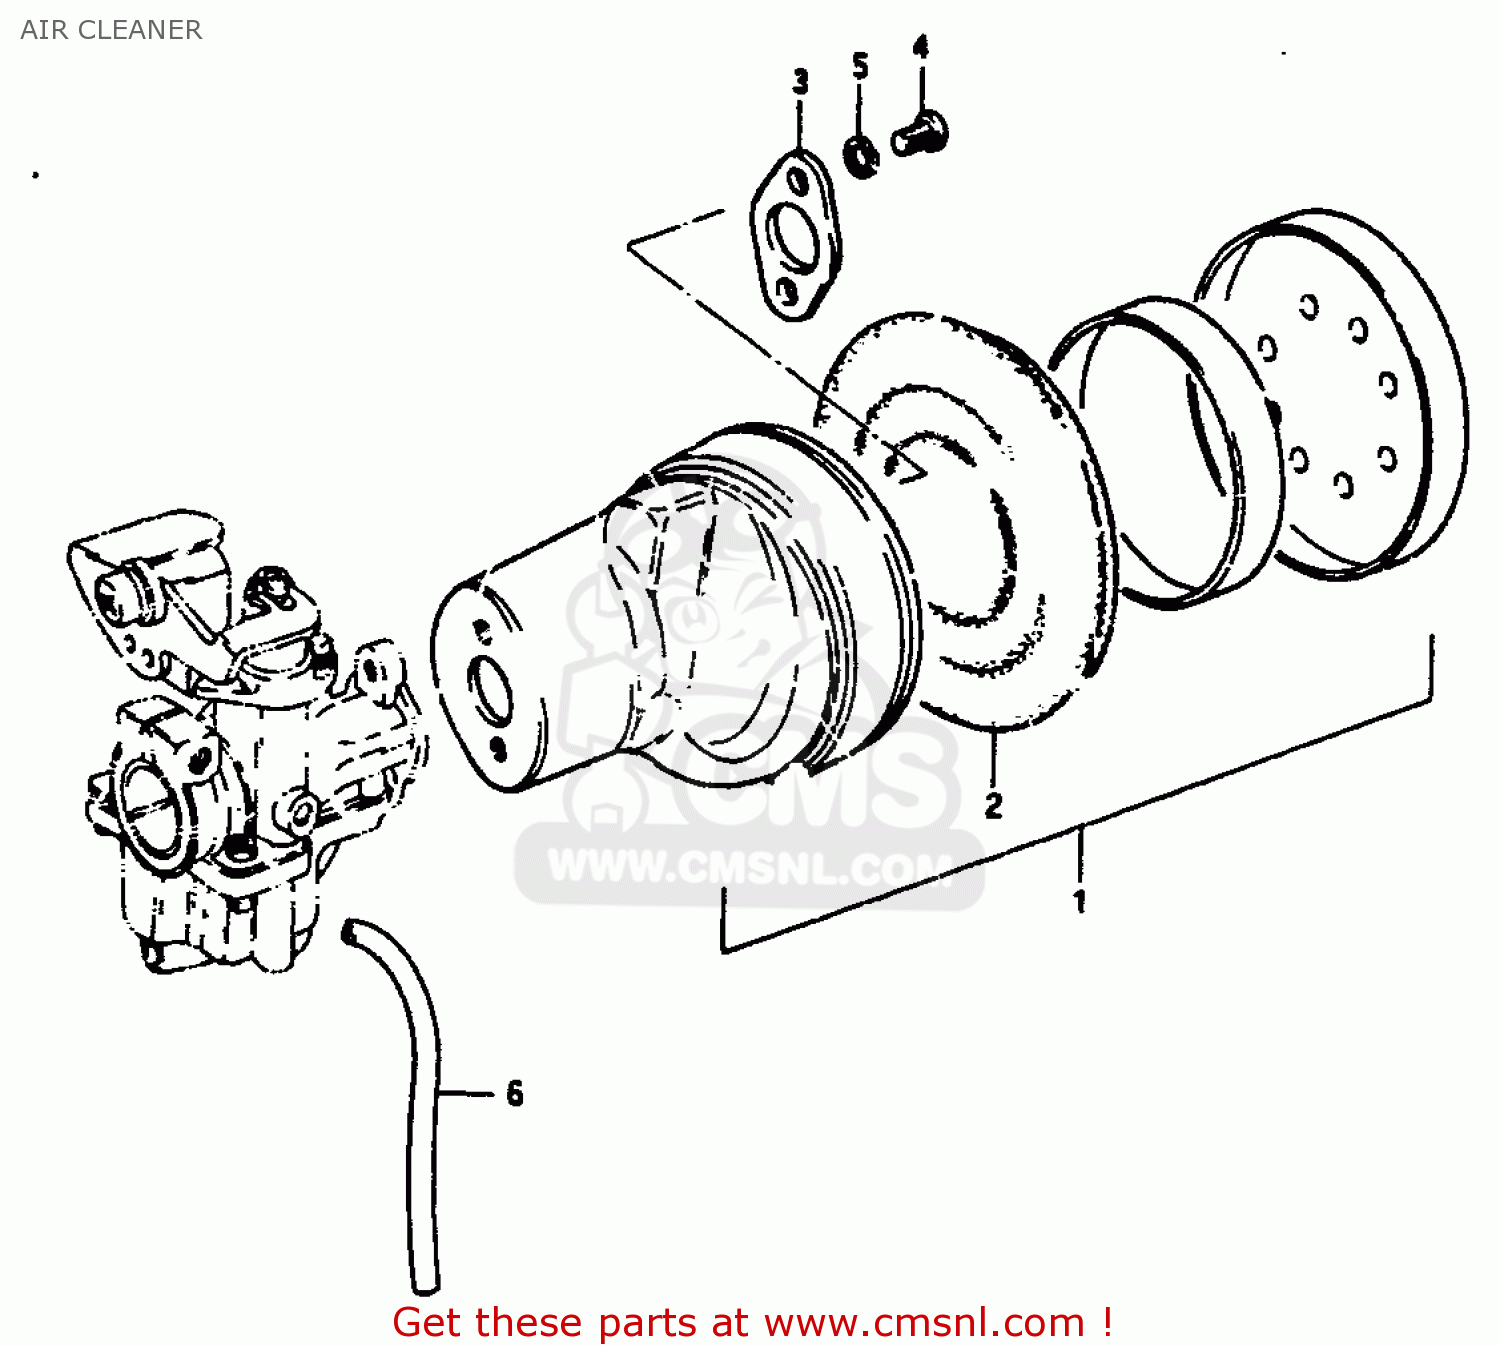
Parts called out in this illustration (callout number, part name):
1	CLEANER ASSY,AIR
2	FILTER,AIR CLEANER
3	PLATE,AIR CLEANER
4	SCREW
5	LOCK WASHER
6	HOSE
